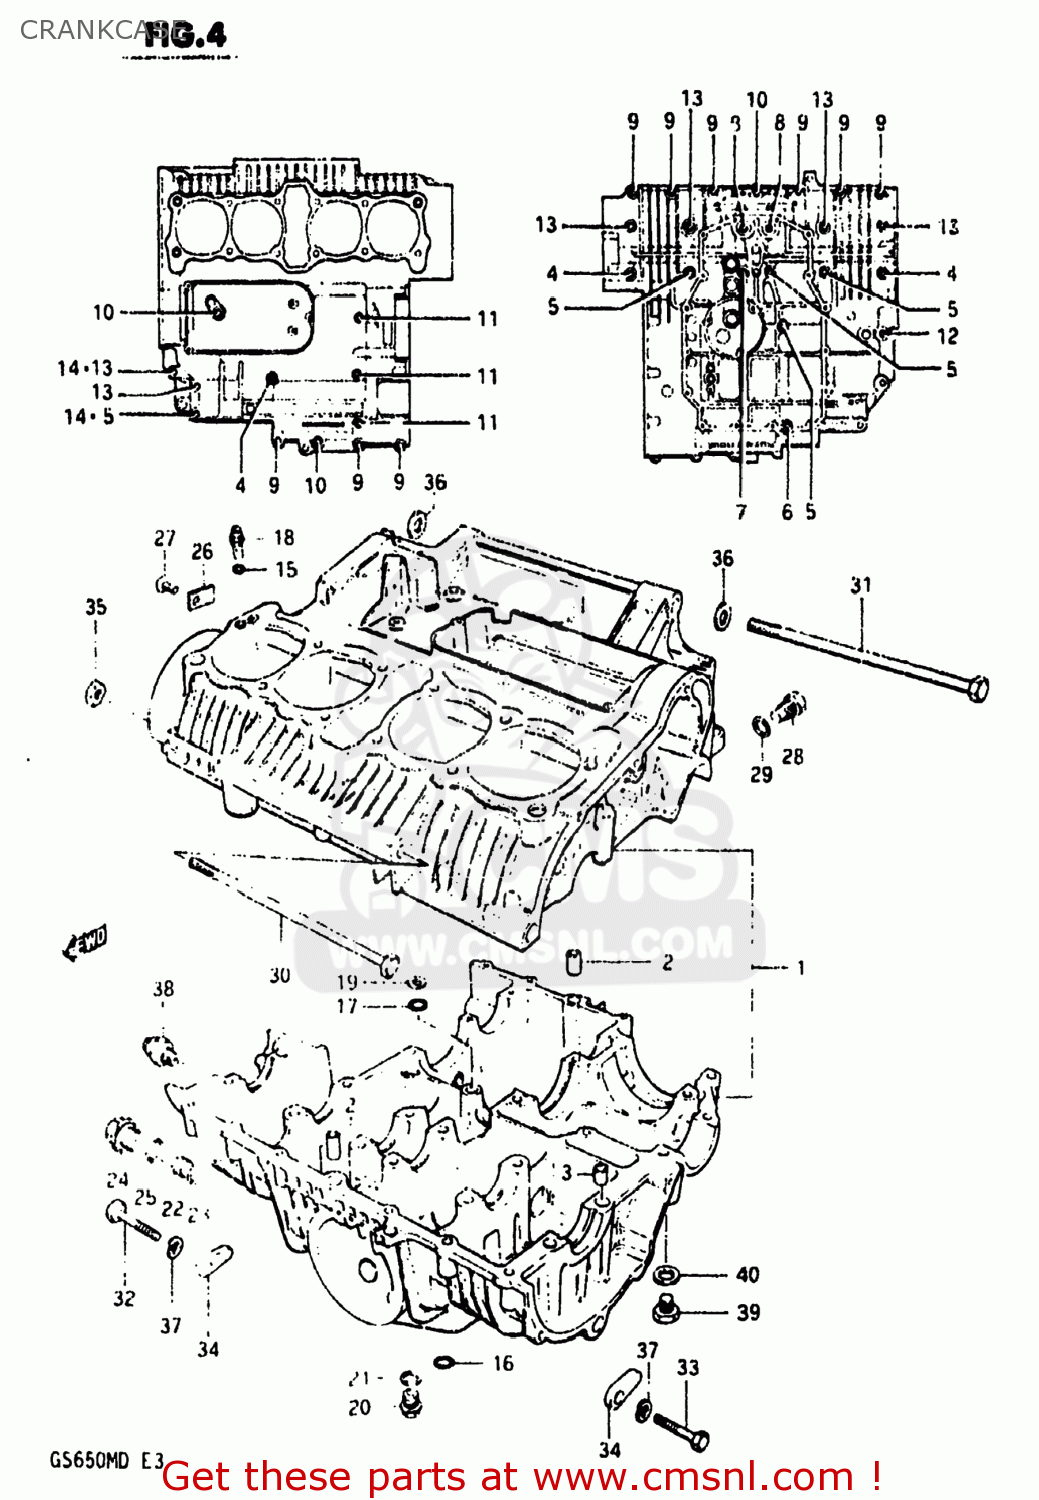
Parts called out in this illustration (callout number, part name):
1	CRANKCASE SET
2	PIN (11X20)(SUS)
3	PIN(10.4X13X22)
4	BOLT
5	BOLT
6	BOLT(8X135)
7	BOLT(8X140)
8	BOLT
9	BOLT (6X40)
10	BOLT 6X55
11	BOLT (6X90)
12	BOLT (8X70)
13	BOLT (8X95)
14	NUT 8MM
15	O-RING,OIL GALLERY JET
16	O-RING
17	O RING(D:3.2,ID:12.9)
18	JET(12)
19	WASHER
20	PLUG
21	GASKET(16X22X2) (NAS)
22	PIN,OIL GALLERY
23	SEAL (D:1.9 ID:9.8)
24	PLUG
25	O RING(D:2.4,ID:17.8)
26	PLATE,OIL GALLERY PLUG
27	SCREW
28	PLUG
29	GASKET(12.1X16.2X3.7) (NAS)
30	BOLT
31	BOLT
32	BOLT 10X55
33	BOLT
34	NUT
35	NUT 10MM
36	WASHER
37	LOCK WASHER
38	SWITCH ASSEMBLY
39	PLUG
40	GASKET(14X19.2X2) (NAS)
